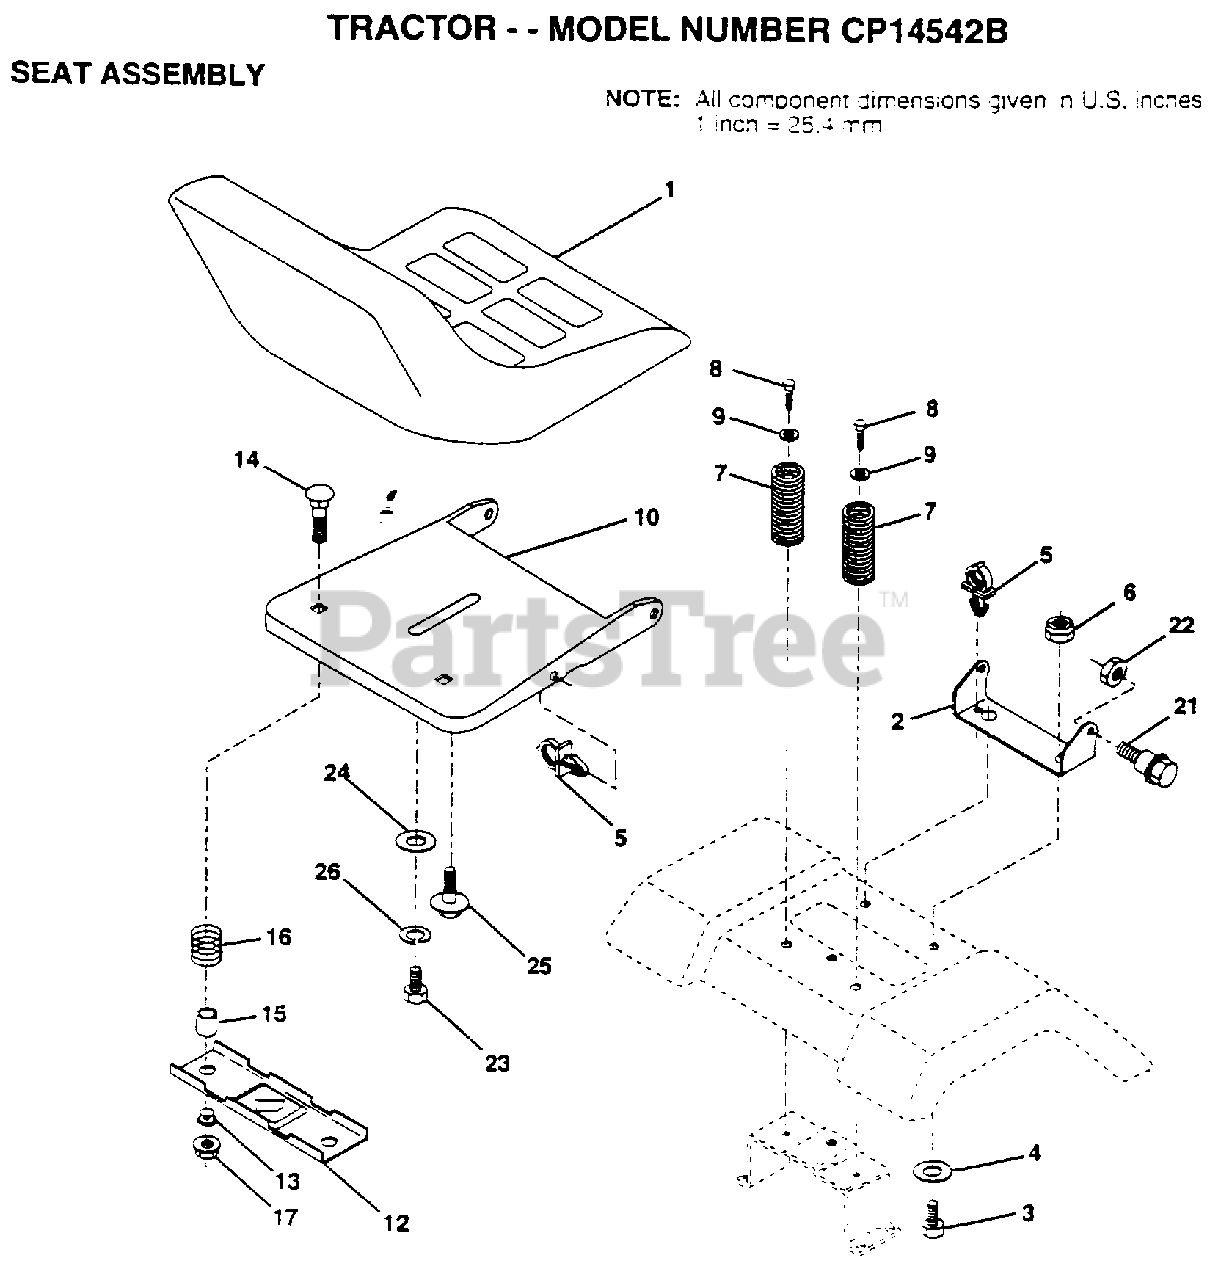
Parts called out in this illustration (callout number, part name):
2	BRACKET PVT SEAT
3	BOLT
4	WASHER PM
5	CLIP.PUSH-IN.HING
6	NUT
7	SPRING COMPRESSIO
8	SCREW GTV
9	WASHER
12	BRKT SWITCH
13	BUSHING
15	SPLIT SPACER
16	SPRING
21	BOLT.SHLD.5/16-18
22	NUT
23	BOLT
24	WASHER
25	"BOLT,SHOULDER"
26	LOCKWASHER
